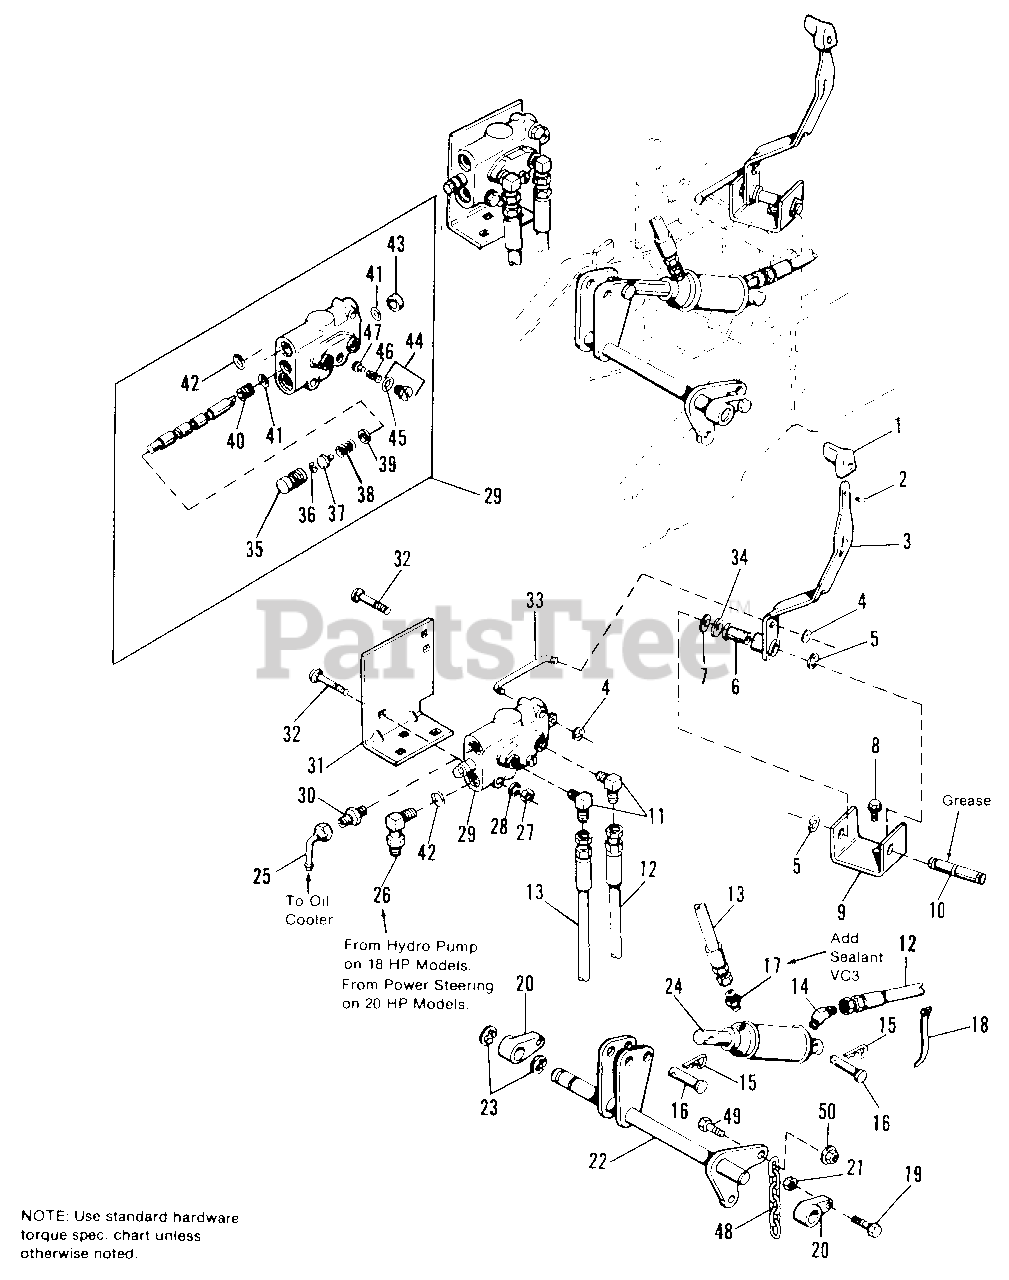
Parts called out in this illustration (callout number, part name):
1	KNOB, Control Handle
2	SCREW, Plastite, 1/4 x 1
3	CONTROL LEVER ASSY.
4	RING, Retaining, "E" Type, 3/16
5	RING, Retaining, "E" Type, 5/8
6	BUSHING, Nylon, 41/64" I.D. x 49/64" O.D. x 1-1/2"
7	WASHER, Spring
8	SCREW, Taptite, 5/16-18 x 3/4
9	BRACKET, Support
10	SHAFT, Control Support
11	FITTING, Hyd.
12	HOSE ASSY., Hyd. (Valve to front of strg. cyl.)
13	HOSE ASSY., Hyd. (Vave to rear of strg. cyl.)
14	FITTING, Elbow 45ø, 1/8-27 x 1/2-70
15	CLIP, Hairpin
16	PIN, Yoke, 5/8 x 2-1/16
17	FITTING, Hyd.
18	TIE, Plastic
19	CAPSCREW, Hex Hd., 5/16-18 x 1-1/4
20	BEARING, Lift Shaft
21	LOCKNUT, Hex, 5/16-18
22	LIFT ASSY., Cylinder
23	"E" RING, Ext.
24	CYLINDER, Hyd., Lift (Incl. Ref. No. 13)
25	FITTING, Hyd.
26	FITTING, Hyd.
27	NUT, Hex, 1/4-20
28	LOCKWASHER, 1/4
29	VALVE ASSY., Control (Incl. Ref. Nos. 26 & 35 thru 47)
30	FITTING, Hyd.
31	PLATE, Valve Mount
32	BOLT, Carriage, 1/4-20 x 2
33	ROD, Control
34	WASHER, Plain, 21/32 I.D. x 1-1/4 O.D. x 1/16
35	CAP, Valve Assy.
36	RING, Retaining
41	"O" RING
43	WIPER, Scraper
44	PLUG & O-RING ASSY. (Incl. Ref. No. 45)
45	"O" RING
47	PLUNGER, Lift Check
48	CHAIN, Lift
49	CAPSCREW, 3/8-16 x 1.0
50	NUT, Hex Flange, 3/8-16
